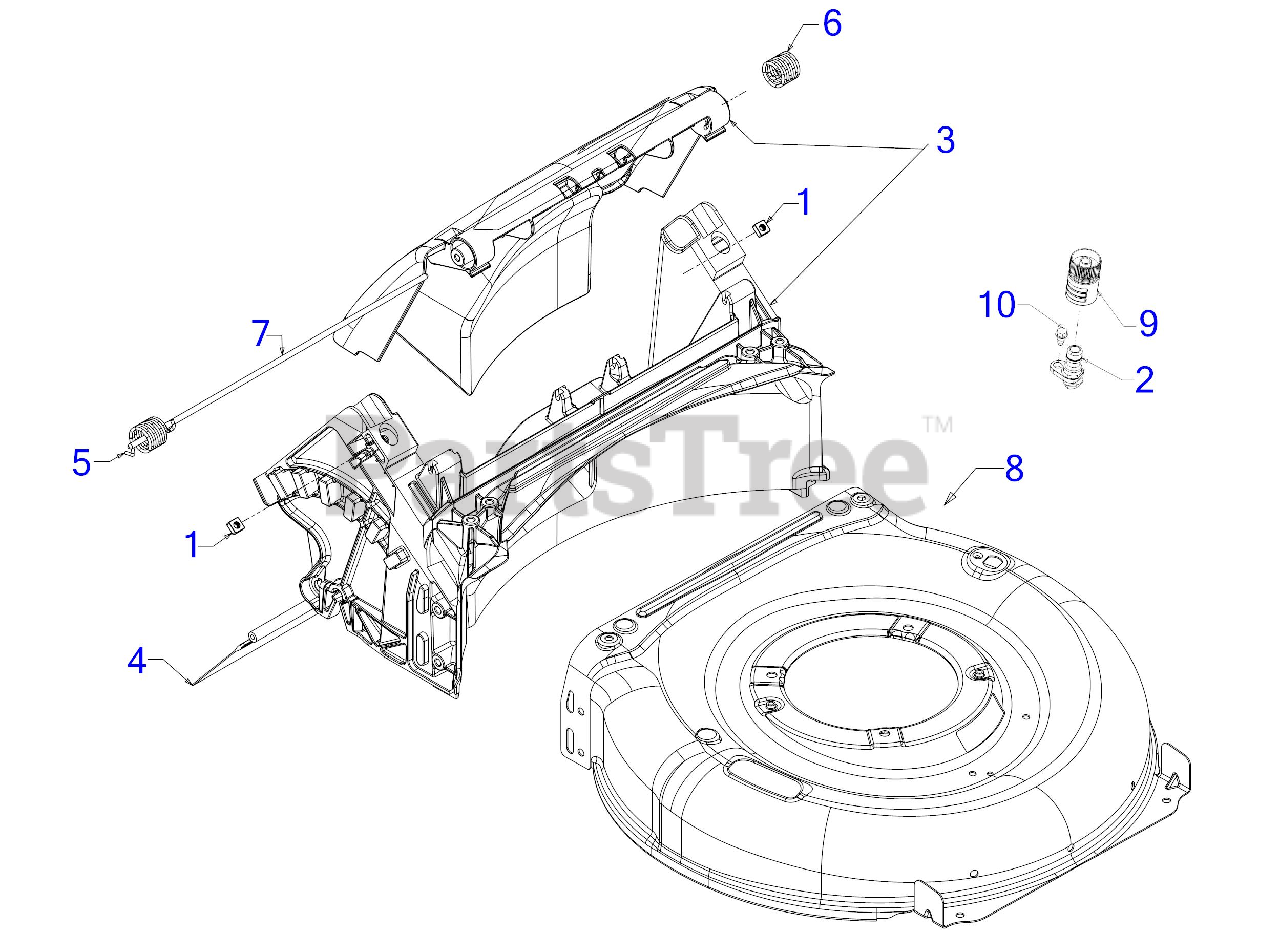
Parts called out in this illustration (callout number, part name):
1	SQUARE NUT 1/4-20
2	DECK WASH NOZZLE
3	REAR BAG DOOR ASSEMBLY
4	TRAILSHIELD
5	TORSION SPRING (RH)
6	TORSION SPRING (LH)
7	REAR DOOR PIVOT ROD
9	WATER NOZZLE
10	SHOULDER SCREW 1/4-20 x .50
